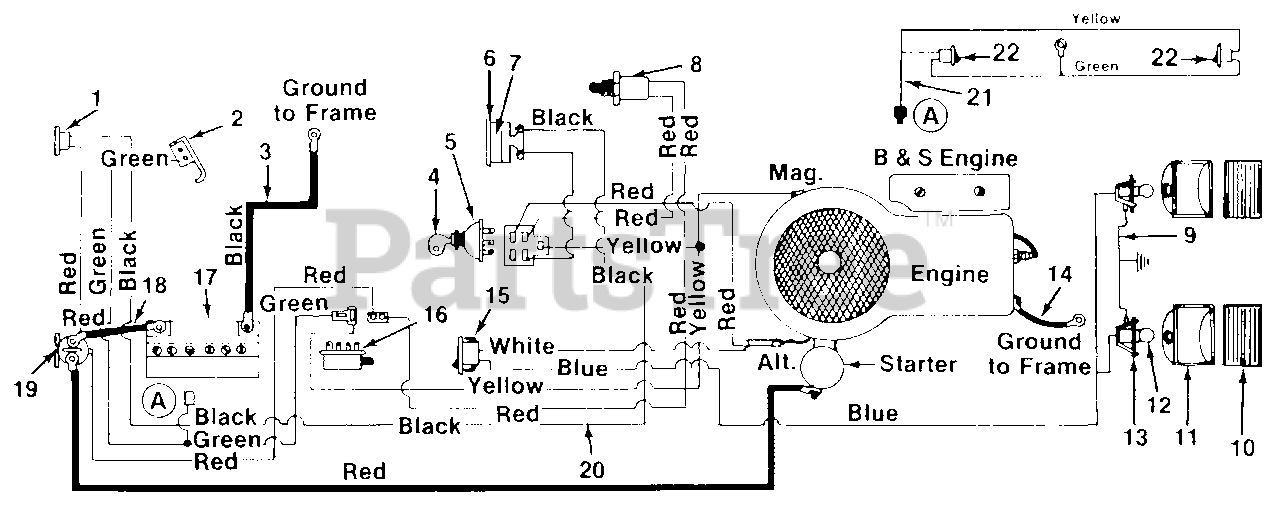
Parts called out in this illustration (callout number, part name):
1	Circuit Breaker
2	Spring-Switch Reverse
3	Ground Wire 9.0" Lg.
4	Ignition Key
5	Ignition Switch
6	Ammeter
7	Foam Strip
8	Safety Switch
9	Ground Wire
10	Lens
11	Headlight Housing
12	Lam p
13	Socket
14	Ground Wire 7.25" Lg.
15	Light Switch
16	Safety Switch
17	Battery
18	Electric Wi re w/Boot
19	Solenoid
20	Wire Harness
21	Wire Lead
22	Safety Switch
